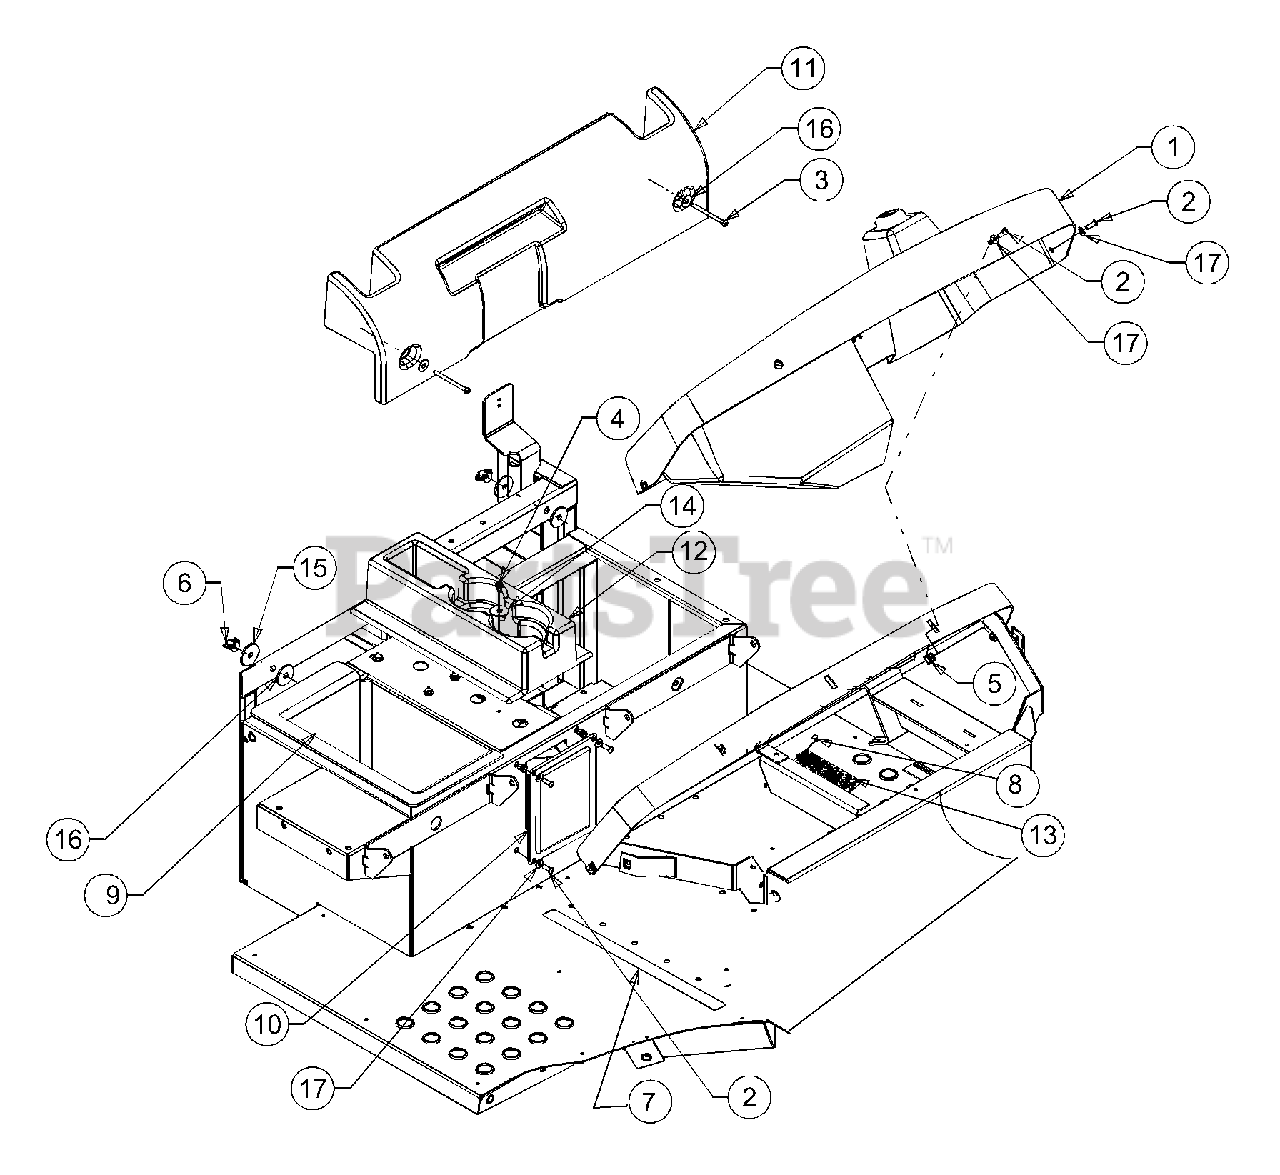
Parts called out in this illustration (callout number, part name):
2	Screw, 1/4-20 x .75
3	Screw, 1/4-20 x 3.0
4	Screw, Self-tapping, 1/4-20 x 0.500
5	Nut, Retainer, 1/4-20
6	Wing Nut, 1/4-20 (w/ Bell Washer)
7	Anti Skid Foot Pad
8	Retainer Clip .250 x .267
9	Tool Box
10	Panel, Shift Cover
11	Panel, Airbox Cover
12	Console, Cup Holder
13	Pad, Foot
14	Flat Washer, .350 x 1.25 x .06
15	Washer, Rubber, .375 x 1.5 x 1.25
16	Washer, Flat, .3125 x .875 x .04
17	Washer, Flat, .271 x .630 x .065
